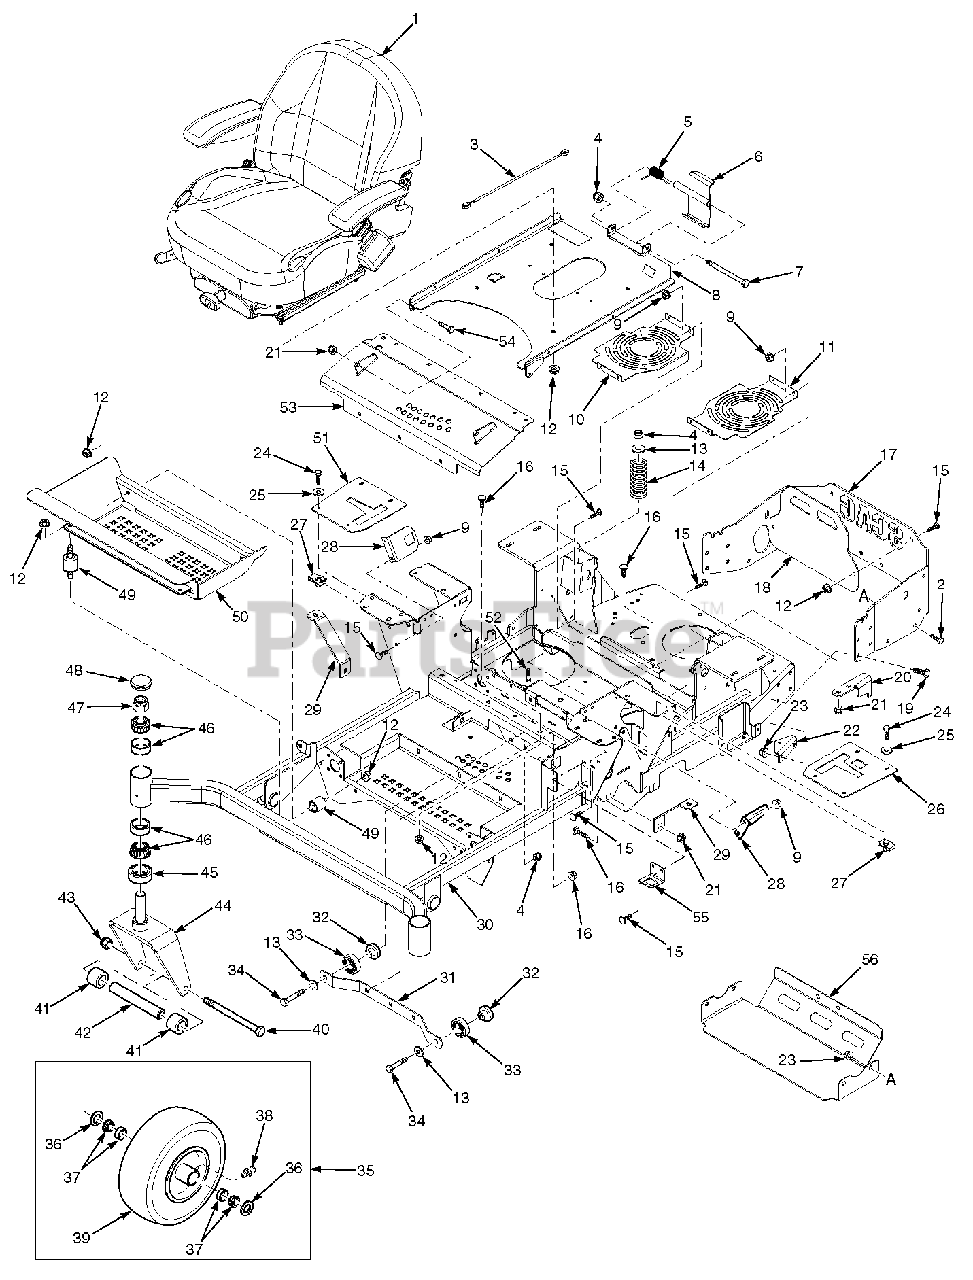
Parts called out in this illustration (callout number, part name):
1	Seat Assembly
2	Bolt, Hex Head 3/8-16 x 3/4"
3	Cable, Seat Stop
4	Nut, Elastic Stop 3/8-16
5	Spring, Seat Latch
6	Weldment, Seat Latch
7	Bolt, Hex Head 3/8-16 x 6"
8	Seat Plate Weldment
9	Nut, Serrated Flange 1/4-20
10	Fan Cover, RH
11	Fan Cover, LH
12	Nut, Serrated Flange 5/16-18
13	Flatwasher, 3/8-.391 x .938 x .105
14	Spring, Seat
15	Bolt, Carriage 1/4-20 x 1"
16	Bolt, Carriage 5/16-18 x 3/4"
17	Bumper - SPZ
18	Guard, Engine
19	Bolt, Hex Head 3/8-16 x 1"
20	Anti-Rotation Bracket
21	Nut, Elastic Stop 5/16-18
22	Bracket, Dump Valve
23	Nut, Serrated Flange 3/8-16
24	Bolt, Hex Head 1/4-20 x 1"
25	Flatwasher, 1/4-.312 x .750 x .065
26	Control Plate w/Decal, LH
27	U-Nut, 1/4-20
28	Bracket, Switch Mount
29	Bracket, Tank Mount, SPZ52
29	Bracket, Tank Mount, SPZ61
30	Mainframe Assy., w/Decals - SPZ52
30	Mainframe Assy., w/Decals - SPZ61
31	Support, Deck Guide
32	Spacer, Bearing
33	Bearing
34	Bolt, Hex Head 3/8-16 x 2-1/2"
35	Wheel Assembly
37	Bearing
38	Fitting, Grease
39	Tire, 13 x 6.5-6
40	Bolt, Hex Head 1/2-13 x 9-1/2"
41	Spacer, Caster Wheel
42	Sleeve, Caster Wheel
43	Nut, Elastic Stop 1/2-13
44	Yoke Weldment
45	Seal, 2" OD x 1.625 ID
46	Bearing Set
47	Nut, Elastic Stop 1"-14
48	Grease Cap
49	Rubber Isolator
50	Footplate Weldment, SPZ52
50	Footplate Weldment, SPZ61
51	Control PLate w/Decal, RH
52	Bolt, Carriage 3/8-16 x 1-1/4"
53	Deck Lift Cover w/Decal, SPZ52
53	Deck Lift Cover w/Decal, SPZ61
54	Bolt, Hex Head 5/16-18 x 3-3/4"
55	Switch Bracket
56	Heat Shield
